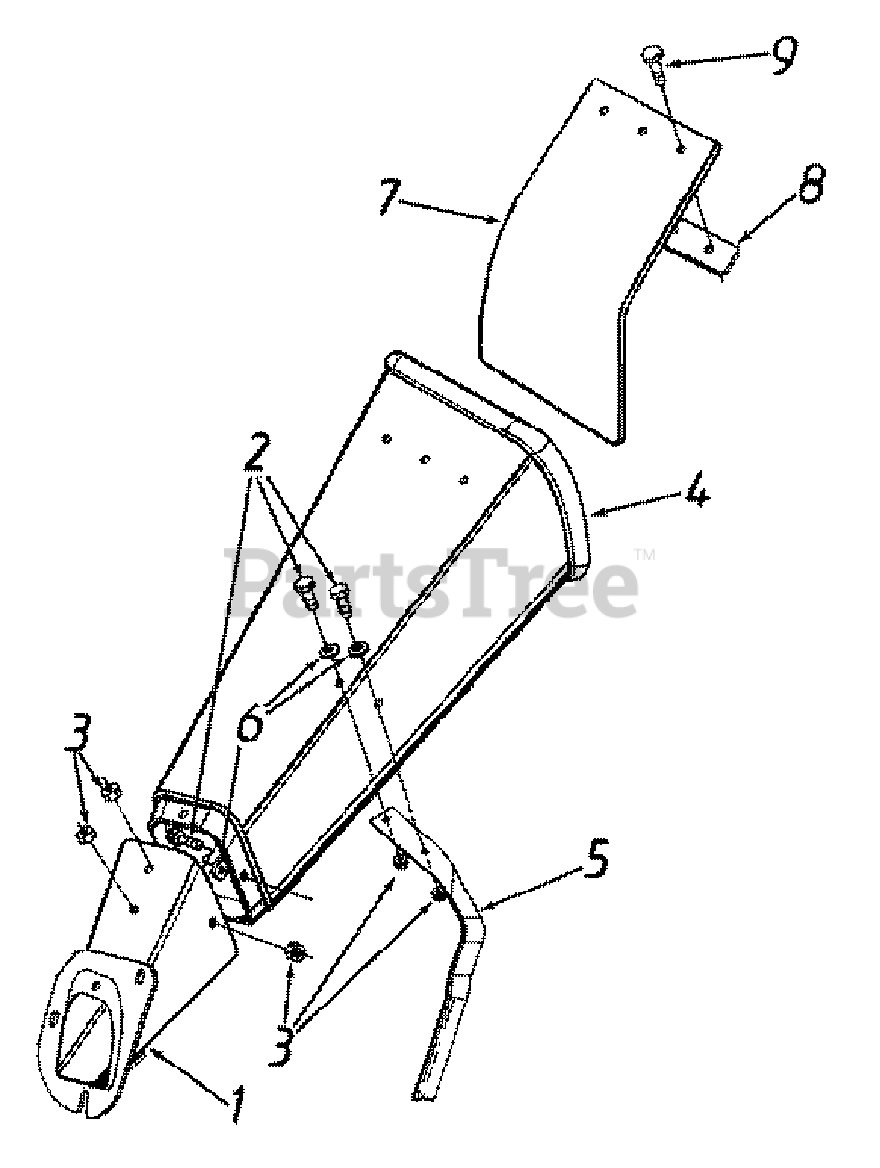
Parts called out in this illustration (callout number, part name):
3	NUT-LOCK
4	CHUTE-CHIPPER UPPER
5	FL-WASH. .28" I.D. x .73" O.D.
8	STRIP-FLAP
9	RIVET
